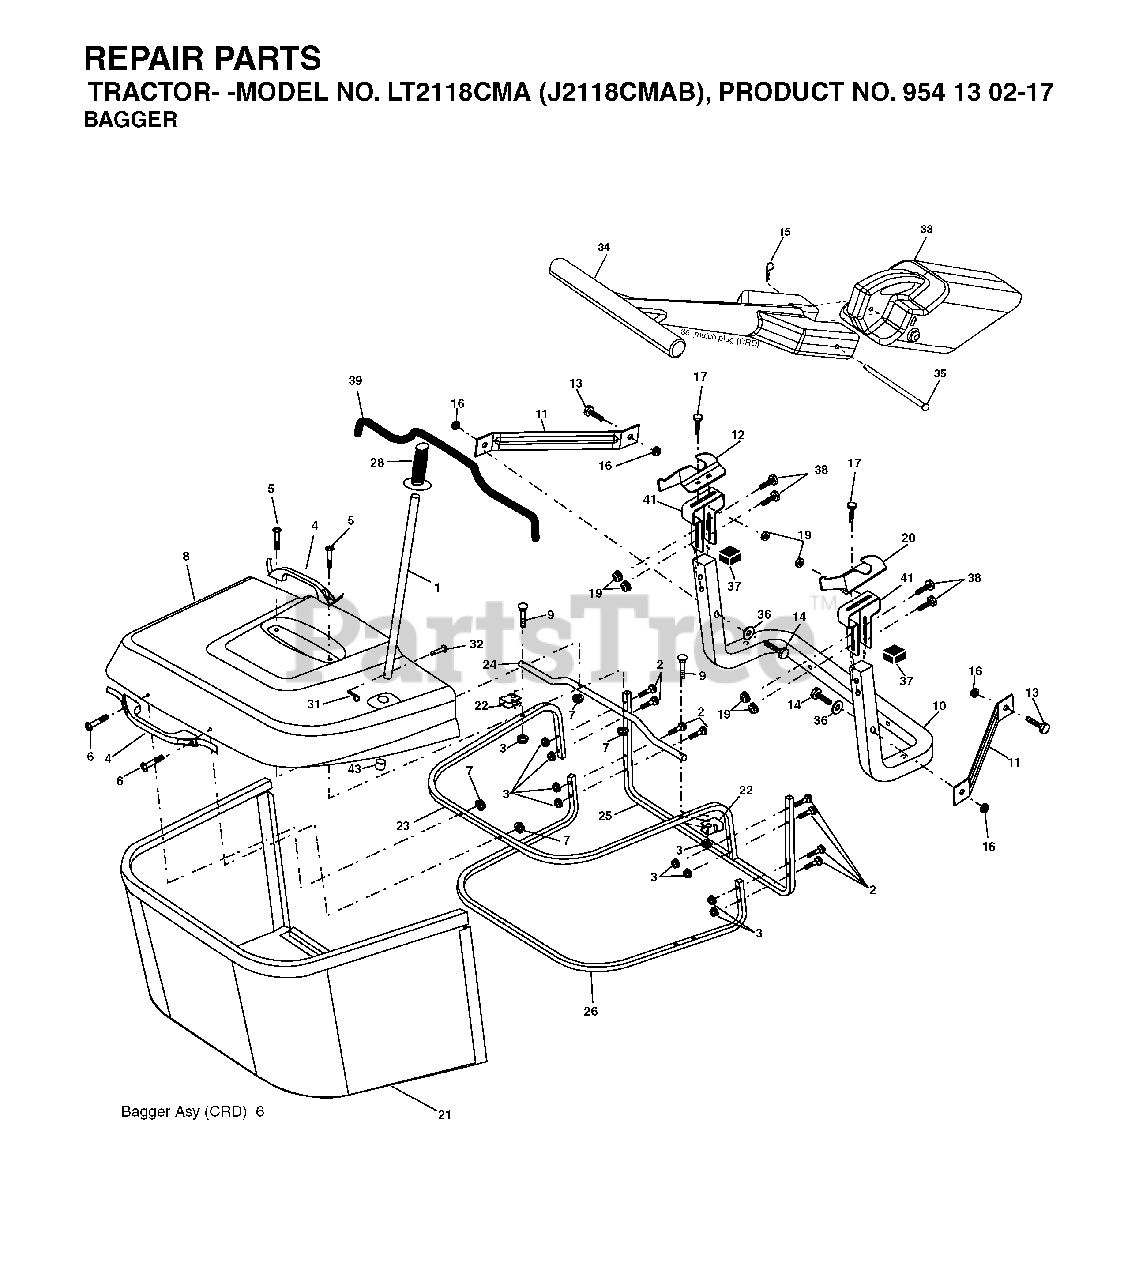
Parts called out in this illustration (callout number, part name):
1	TUBE HANDLE
3	NUT T
5	SCREW.PAN.HEAD
11	BRACKET
14	BOLT-HEX EAK
15	RETAINER-SPRNG RB
16	NUT LOCK FLG 3/8-16 UNC
17	BOLT
19	NUT LOCK HEX FLANGE 5/16-18
20	BRKT.PIVOT.RH.CRD
21	GRASS BAG
22	BRACKET
23	TUBE
24	TUBE
26	TUBE
28	GRIP.HANDLE.BLACK
31	RETAINER CLIP
32	RIVET,DRILLED
33	MULCH PLUG, CTH150
35	PIN
36	WASHER
38	BOLT.5/16-18X2.5
41	BRKT, BAGGER
42	NUT.71038.31-18.HEX.NYLOCK
43	PLUG, TUBING END
